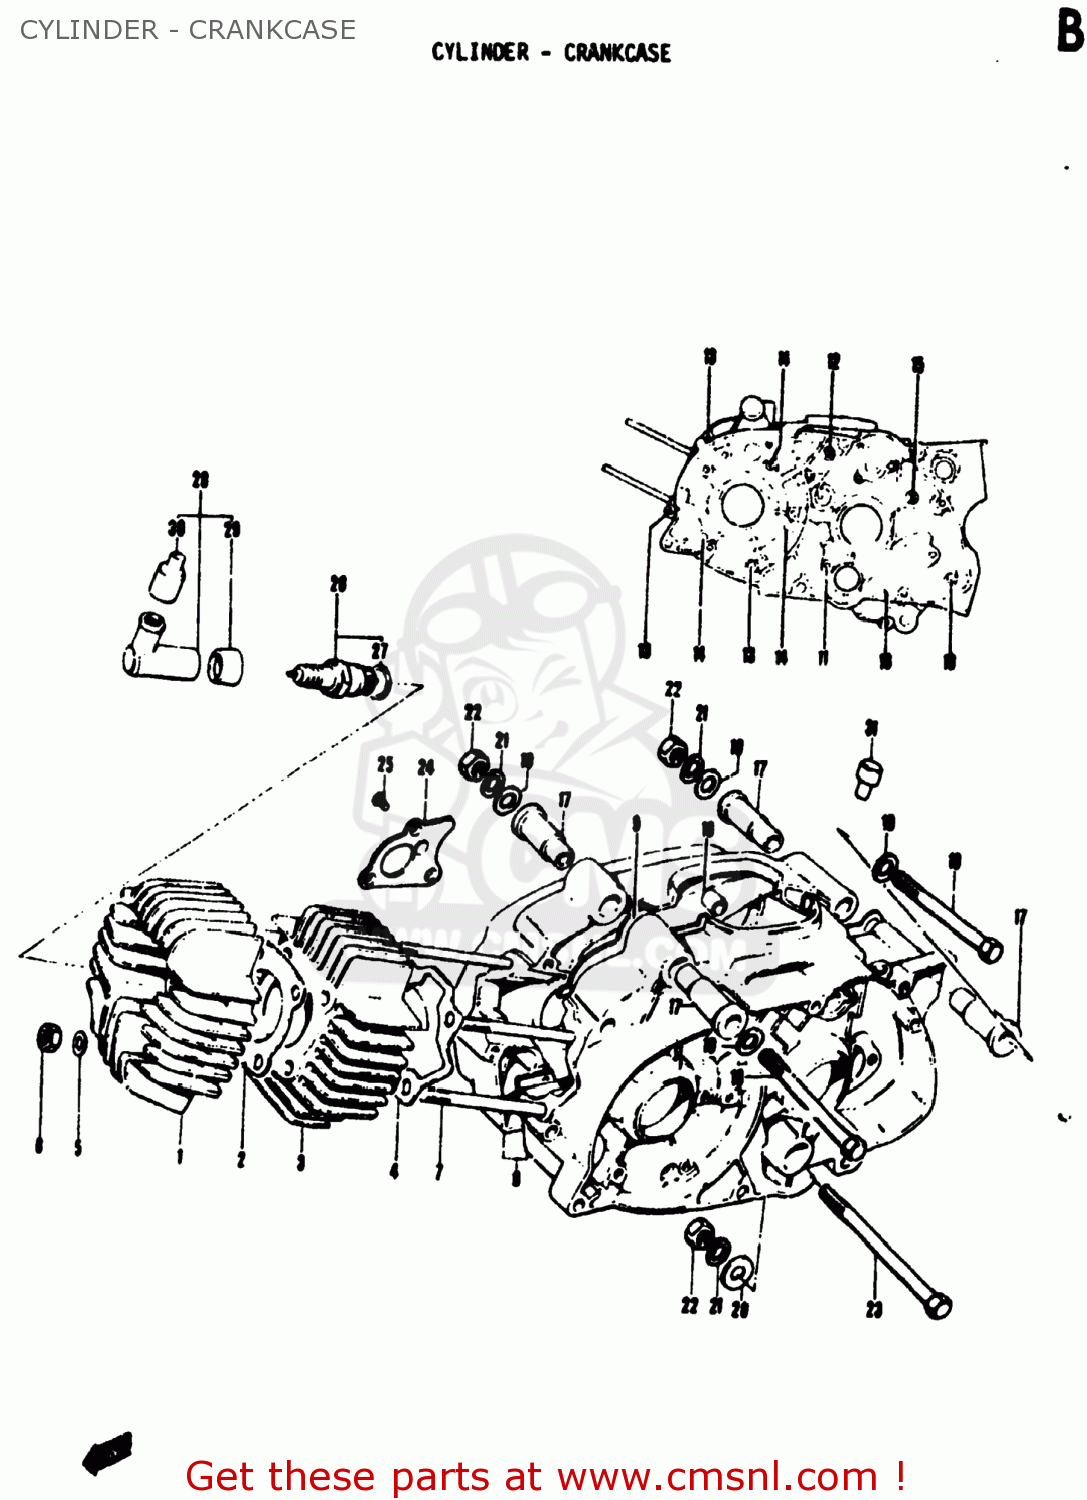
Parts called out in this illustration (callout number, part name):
1	HEAD,CYLINDER
2	GASKET,CYLINDER HEAD (NAS)
3	CYLINDER
4	GASKET,CYLINDE (MCA)
5	WASHER
6	NUT
7	STUD 6X95
8	CRANKCASE SET
10	PIN
11	SCREW 6X60
12	SCREW
13	SCREW (6X45)
14	SCREW
15	SCREW (6X35)
16	SCREW
17	BUSHING
18	BOLT 8X100
19	WASHER
20	WASHER
21	LOCK WASHER
22	NUT
23	BOLT 8X110
24	PLATE,OIL RESERVOIR
25	SCREW
26	SPARK PLUG
27	GASKET(13.8X18.8X4.8) (NAS)
28	CAP,SPARK PLUG
29	SEAL,SPARK PLUG
30	SEAL,SPARK PLU
31	CAP(OD:15)
